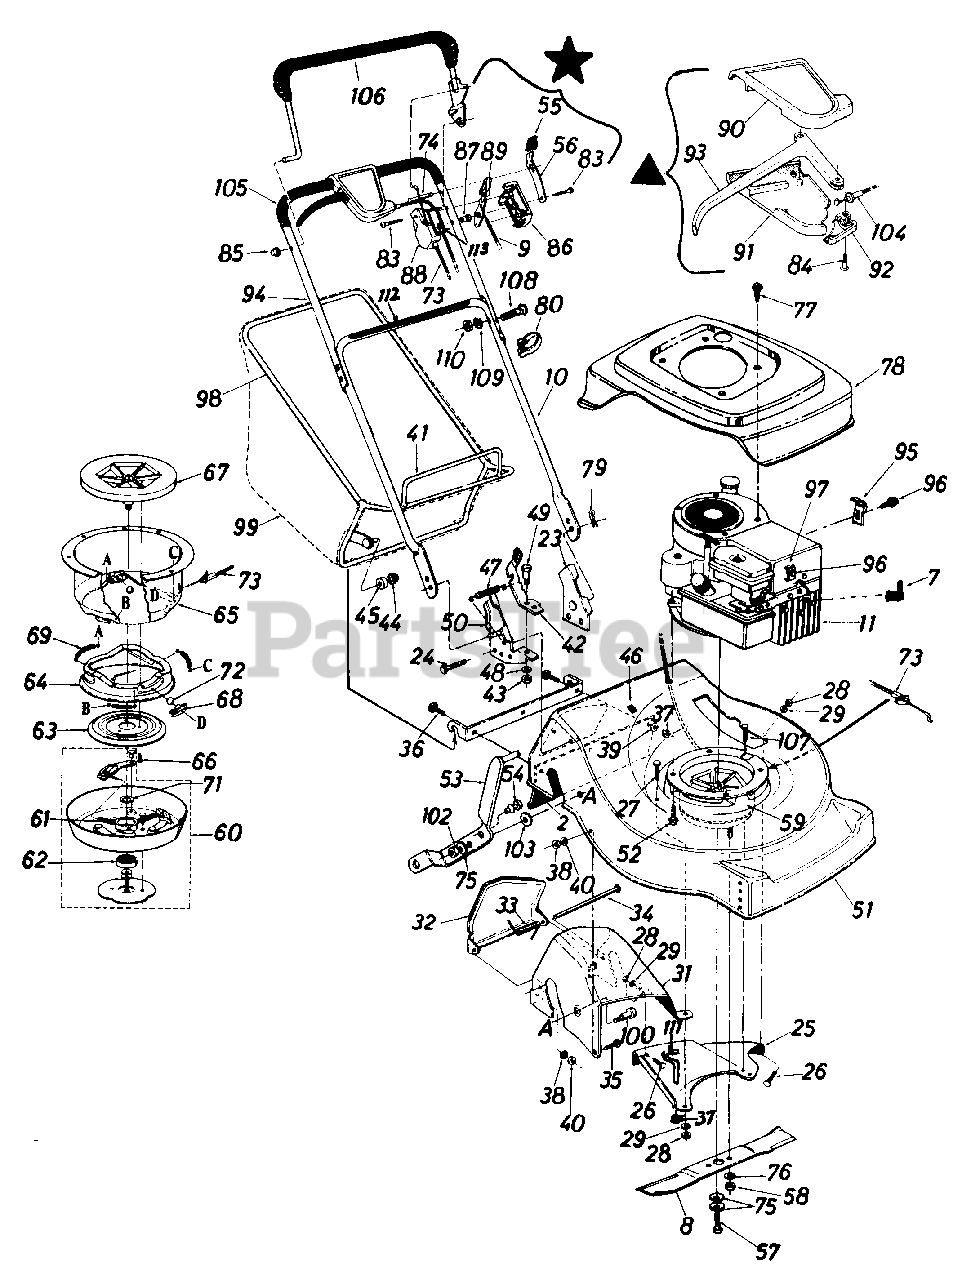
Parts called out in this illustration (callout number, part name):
2	Rear Flap Ass'y.
7	Spark Plug Boot
8	22" Blade
9	Throttle Control Wire - 58"
10	Lower Handle
11	Engine
23	Handle Brkt. Ass'y. - L.H.
24	Hex Wash. Hd. AB-Tap Scr. 1/4" x .62" Lg.
25	Rear Baffle - L.H.
26	Carriage Bolt 1/4-20 x .50" Lg.
27	Hex Bolt 1/4-20 x .88" Lg.
28	Hex Nut 1/4-20 Thd.
29	L-Wash. 1/4" I.D.
31	Rear Chute Baffle Ass'y.
32	Chute Door
33	Torsion Spring
34	Hinge Pin .250" Dia. 7.88" Lg.
35	Carriage Bolt 1/4-20 x .50" Lg.
36	Carriage Bolt 1/4-20 x .75" Lg.
37	Sems Nut 1/4-20 Thd.
38	Hex Nut 1/4-20 Thd.
39	Fl-Wash. .285" I.D. x 1.25" O.D.
40	L-Wash. 1/4" I.D.
43	Hex Nut 5/16-18 Thd.
44	Push Nut 3/8" Rod
45	Plastic Roller
47	Extension Spring .33" O.D. x 1.12" Lg.
48	L-Wash. 5/16" I.D.
49	Shld. Bolt .437" Dia. x .162" Lg.
50	Handle Brkt. Ass'y. - R.H.
51	22" Deck Ass'y.
52	Hex Wash. Hd. TT-Tap Scr. 3/8-16 x 1.0" Lg.
53	Rear Wheel Pivot Brkt. Ass'y
54	Rubber Bumper
55	Spring Lever Knob
56	Lockout Lever
57	Hex Bolt 3/8-24 x 2.00" Lg. (Grade 8)
58	Hex Nut 3/8-24 Thd. (Grade 8)
59	Blade Brake Clutch Ass'y. Comp.
60	Clutch Blade Housing Ass'y.
61	Compression Spring .35" O.D. x 2.00" Lg.
62	Ball Brg. .669" I.D. x 1.574" O.D. x .47
63	Clutching Cone
64	Brake Cup Cone
65	Clutch Housing
66	Hex TT-Tap L-Scr. 1/4-20 x .75" Lg.
67	Fan Adapter
68	Ball Block
69	Extension Spring .35" O.D. x 1.75" Lg.
71	Fl-Wash. .690" I.D. x 1.060" O.D.
72	Steel Ball .500" Dia.
73	Clutch Cable - 46"
74	Lock Pin .314" Dia. x 1.70" Lg.
75	Bell-Wash. .44" I.D. x .88" O.D.
76	L-Wash. 3/8" I.D.
77	Hex Wash. Hd. AB-Tap Scr. #8 x .50" Lg.
78	Engine Shroud
79	Intern. Cot. Pin 5/16" Dia.
80	Cable Tie
83	Truss Mach. Scr. #12 x 1.50" Lg.
84	Flat "C"-Sunk Hd. Scr. #10 x 1.0" Lg.
85	Cap Speed Nut 5/16" Rod
86	Control Panel Half
87	Control Disc Pin
88	Clutch Panel Half
89	Throttle Control Lever
90	Control Cover Half - Upper
91	Control Cover Half - Lower
92	Cable Mtg. Cap
93	Control Lever
94	Upper Handle
95	Casing Clamp
96	Hex B-Tap Scr. #10 x .38" Lg.
97	Casing Clamp
98	Grass Catcher Upper Frame
99	Grass Catcher Bag
100	Shld. Bolt .500" Dia. x .685" Lg.
103	Bell-Wash. .400" I.D.
104	Clutch Cable - 50"
106	Blade Clutch Control Handle
107	Hex Wash. Hd. Self-Tap Scr. 1/4-20 x .75" Lg.
108	Curved Hd. Carr. Bolt 5/16-18 x 1.38
109	L-Wash. 5/16" I.D.
110	Hex Nut 5/16-18 Thd.
111	Pulley Scraper Finger
112	Control Label-Handle
113	Control Label-Throttle
